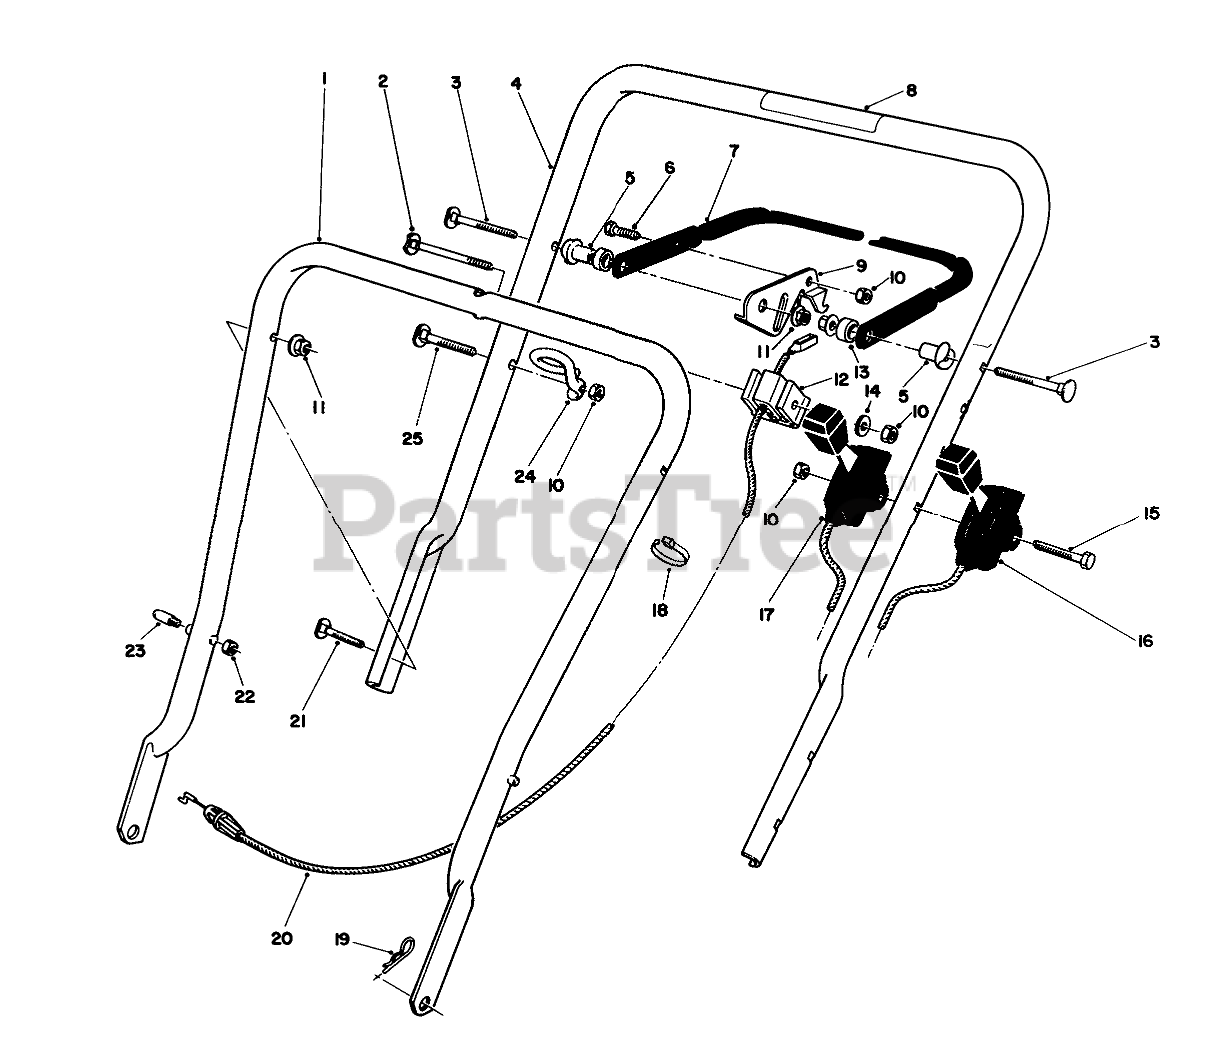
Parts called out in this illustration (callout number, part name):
1	LOWER HANDLE ASM
2	HANDLE SCREW
3	5/16-18 X 2 HNDLE SCREW
4	Handle-Upper (Incl. Ref. #8)
5	SPACER-SUPPORT
6	SCREW-HH
7	Bar-Control
8	WARNING DECAL
9	LEVER-CONTROL
10	NUT-LOCK, NI
11	NUT-LOCK, NI
12	SUPPORT-CABLE
13	SPACER-NYLON
14	WASHER-FLAT
15	SCREW-HH
16	TRACTION CONTROL
17	THROTTLE CONTROL
18	TIE-CABLE
19	PIN-COTTER, HAIR
20	OBS BRAKE CONTROL
21	SCREW
22	NUT-LOCK, NI
23	HANDLE PIN
24	Guide
25	HANDLE SCREW
